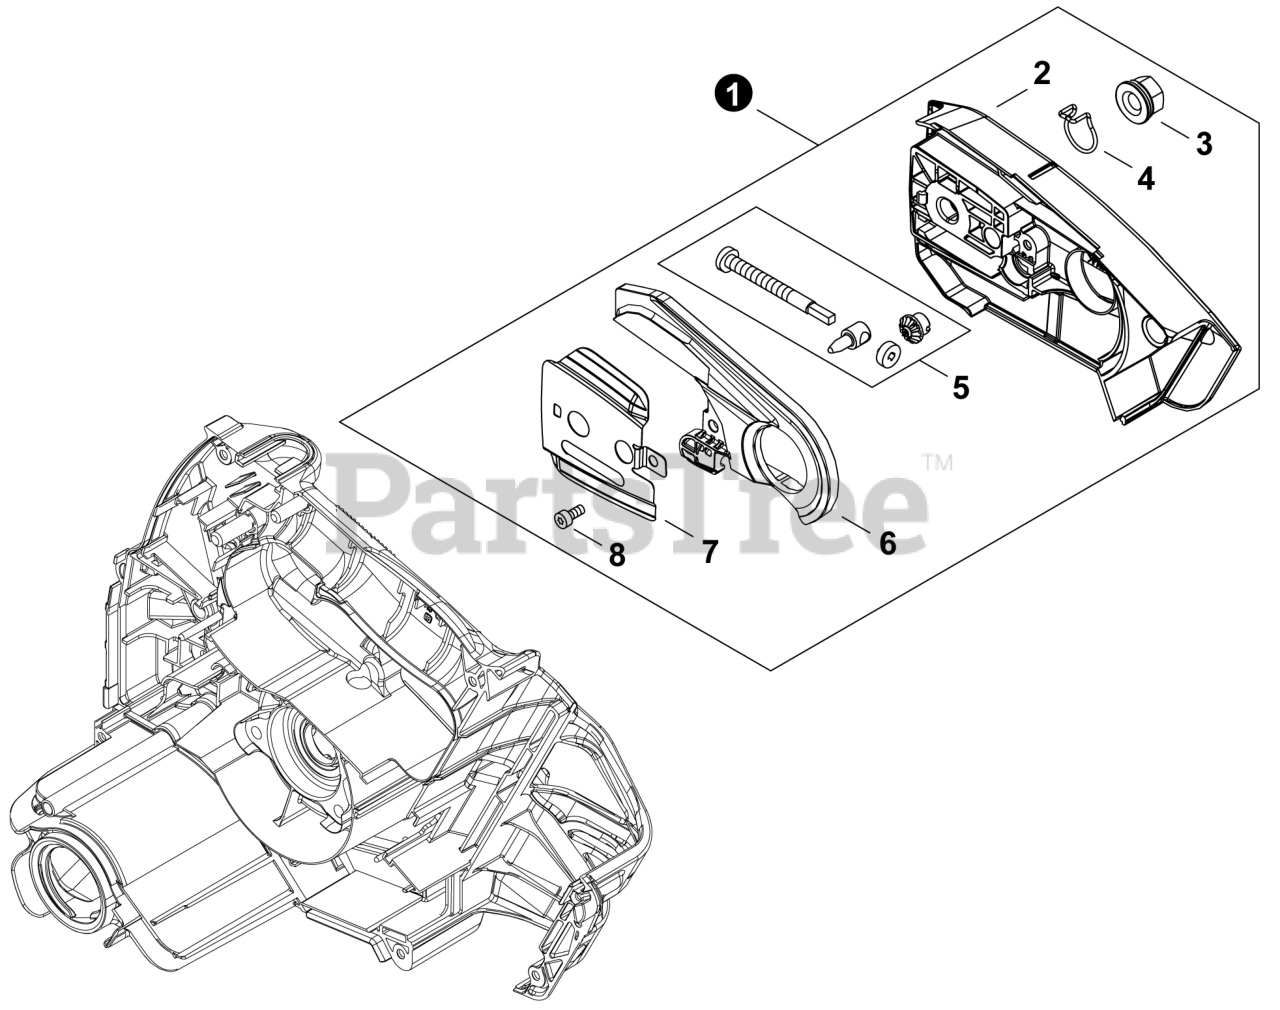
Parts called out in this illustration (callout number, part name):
1	SPROCKET GUARD ASSY
2	GUARD, SPROCKET
5	TENSIONER KIT, CHAIN
6	SHIELD, DEBRIS
7	PLATE, GUIDE - OUTER
8	BOLT, TORX 4x12
